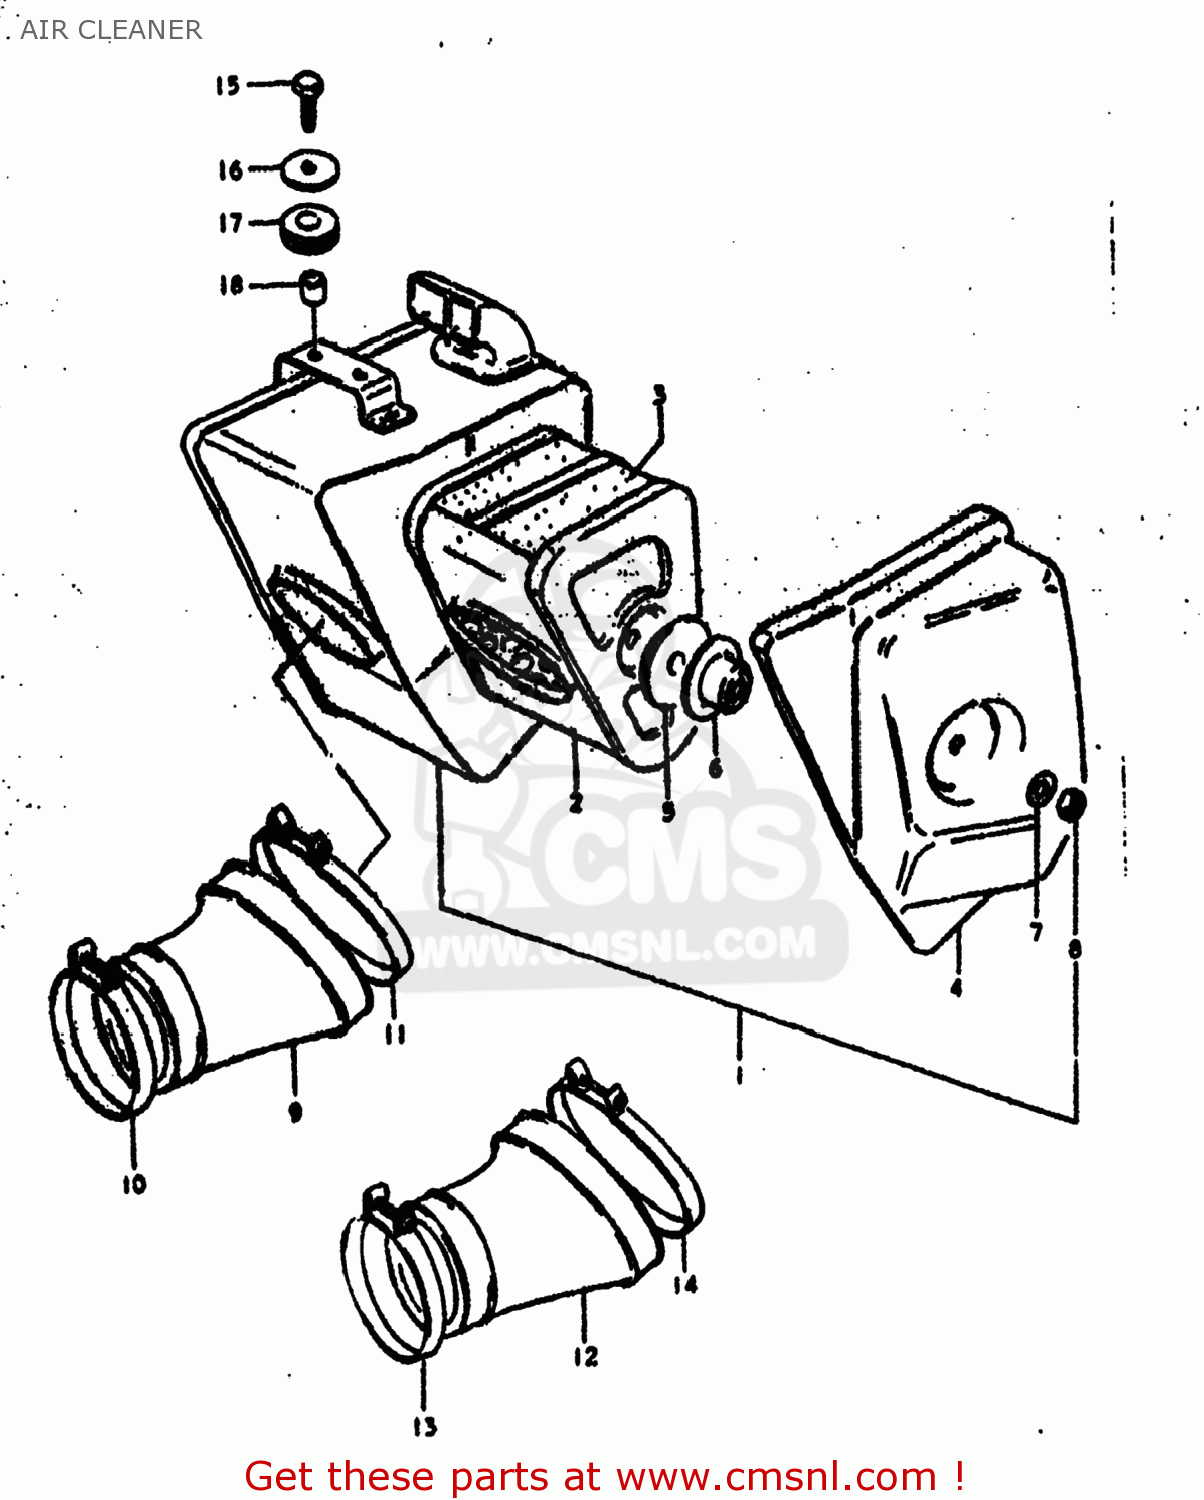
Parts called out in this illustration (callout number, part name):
1	CLEANER ASSEMBLY,AIR
2	FILTER ASSY,AIR CLEANER
3	FILTER
4	CAP
5	SEAL
6	SPACER
7	WASHER
8	NUT
9	HOSE,CARBURETOR AIR INLET
10	CLAMP
11	CLAMP
12	TUBE,AIR CLEANER OUTLET
13	CLAMP
14	CLAMP
15	BOLT
16	WASHER
17	CUSHION
18	SPACER (7X9X7)
